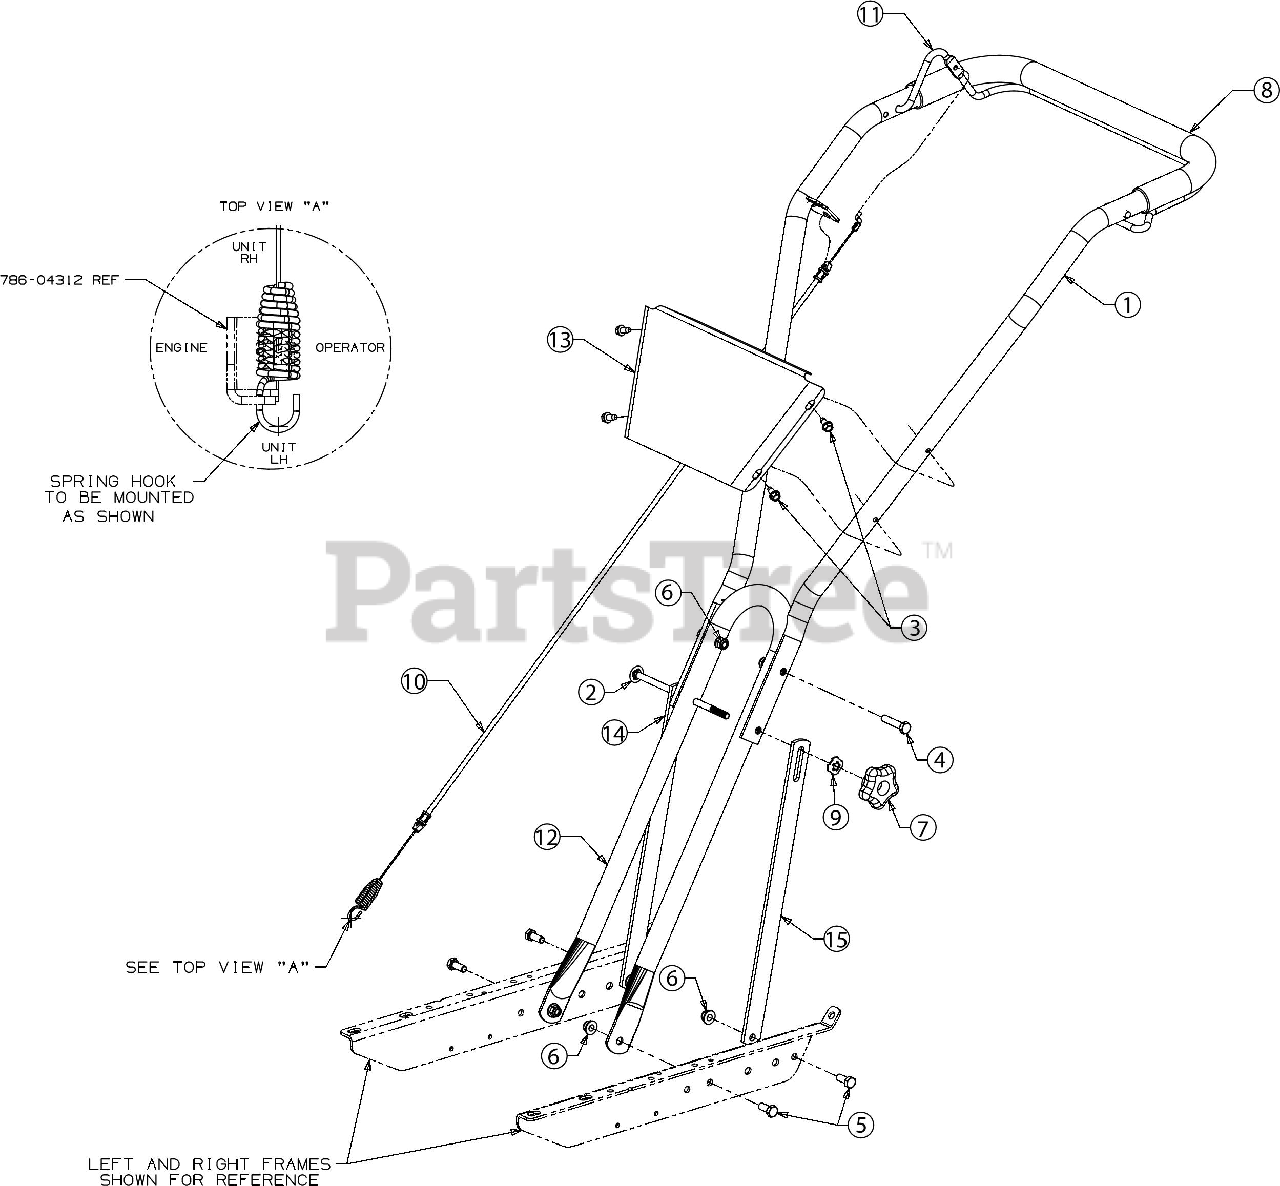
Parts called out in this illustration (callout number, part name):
1	UPPER HANDLE ASSEMBLY
2	SCREW 5/16-18 x 6.75
3	SCREW 1/4-20 X.500
4	SCREW 5/16-18 x 1.5 LG
5	SCREW 5/16-18 x .75 GR5
6	FLANGE LOCK NUT 5/16-18
7	STAR KNOB 5/16-18
8	HANDLE GRIP
9	SPECIAL WASHER
10	FORWARD CABLE
15	SUPPORT BRACKET
